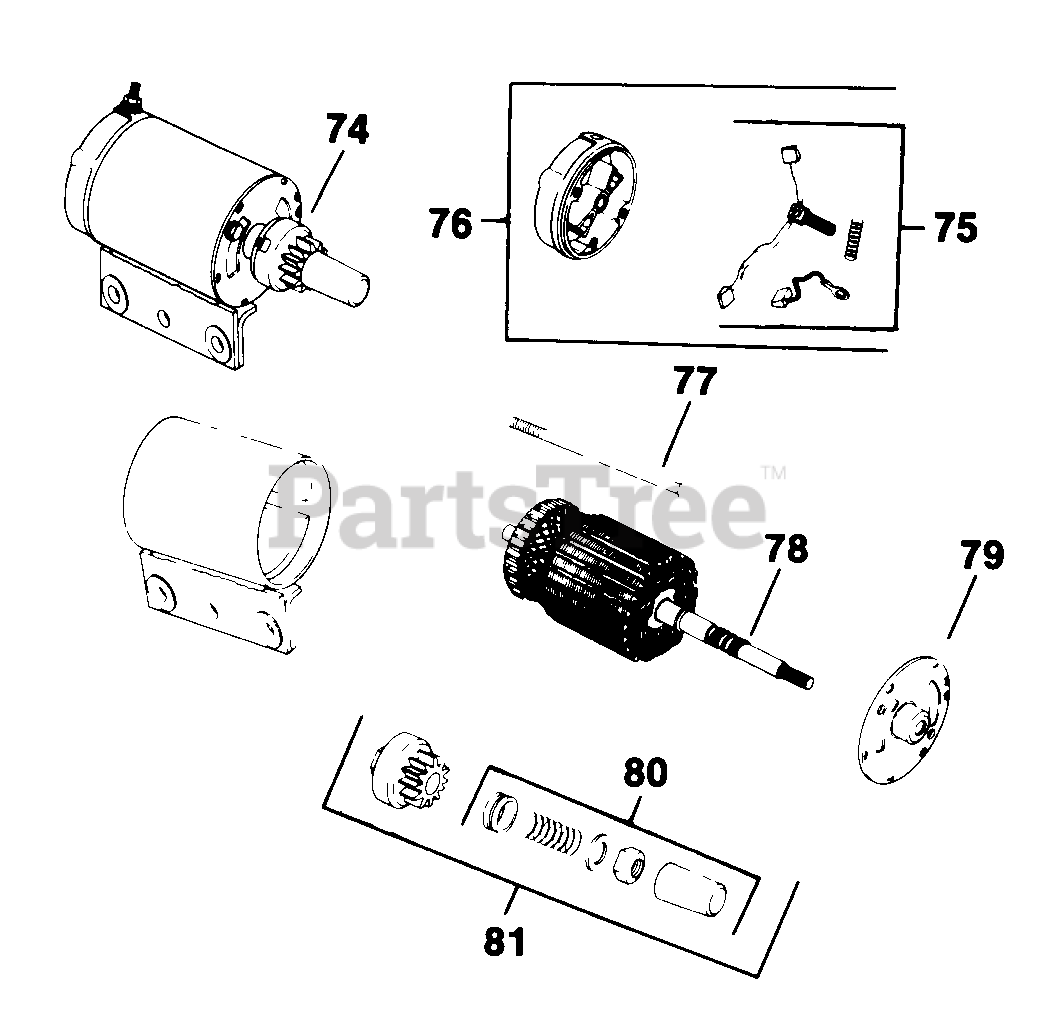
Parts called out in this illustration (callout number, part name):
74	STARTER - USE 45 098 07
75	KIT - USE 52 755 15
76	CAP - DISCONTINUED
79	CAP - USE 45 081 05
